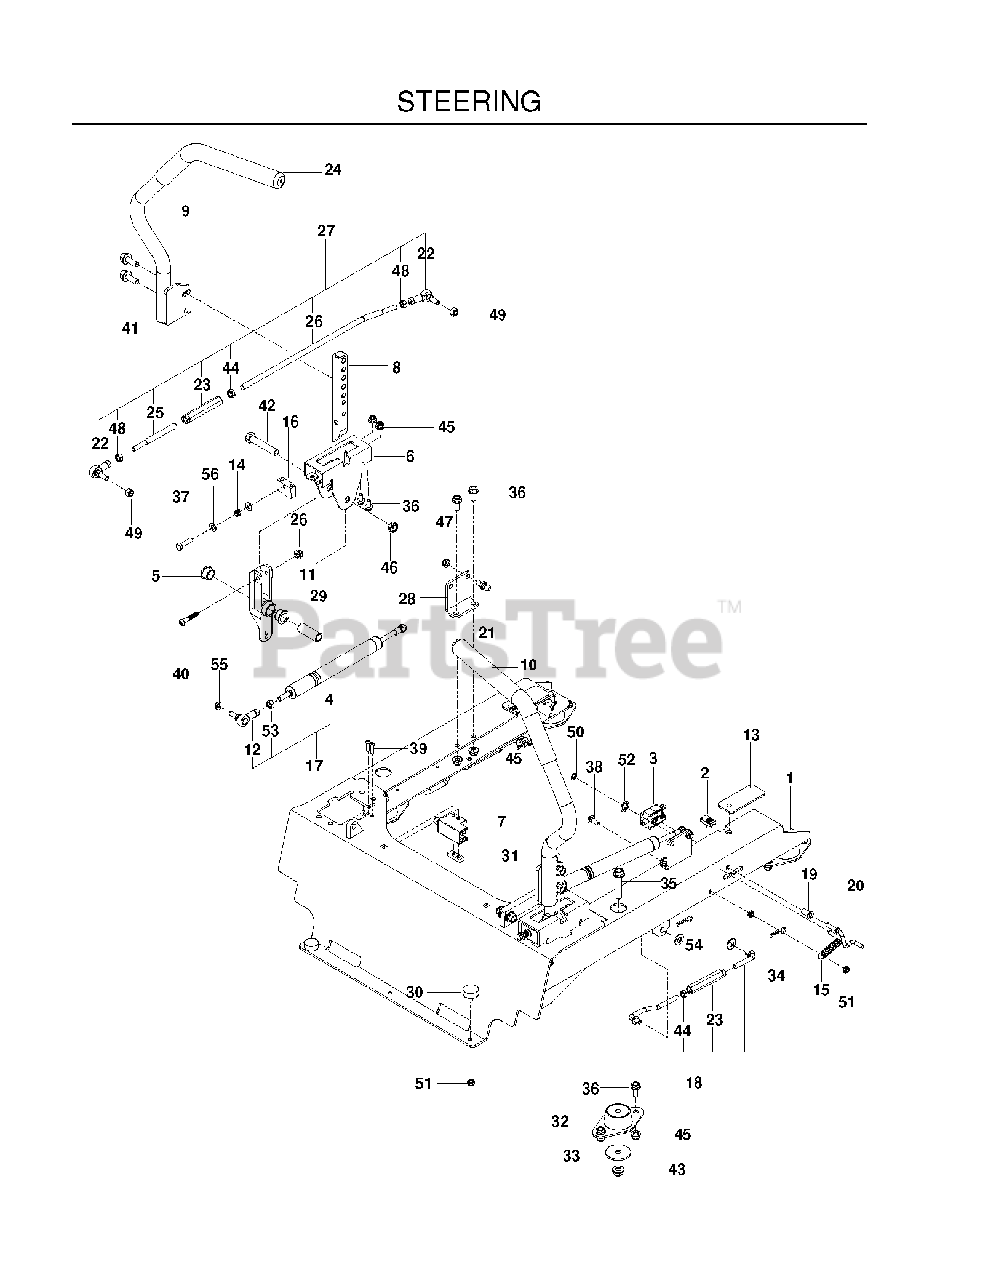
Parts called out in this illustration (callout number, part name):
2	U-CLIP 5/16-18 NUT RETAINER
3	SWITCH, BRAKE 3P
4	DAMPENER
5	BEARING, FLANGE
8	LEVER, MOTION
12	ROD END
15	SPRING, EXTENSION
17	ASSEMBLY, DAMPENER
18	ASSEMBLY, SEAT STRUT
19	BUSHING, 1/4 FLANGE
20	LINK, SWITCH
21	10MM BALL STUD
22	SPHERICAL ROD END, RH
23	TURNBUCKLE, 3/8
24	GRIP - DRIVE LEVER
25	LINKAGE, CONTROL, FT
31	TAPPED PLATE
33	WASHER, 3/8 SPEC
34	HAIRPIN #2
35	HHFS 3/8-16 X 2.0 GD 5
36	HHFS 5/16-18 X 3/4
37	HCS 5/16C X 1 1/4
38	RHSNB 1/4C X 3/4
39	SCR #10-24 X .75 SKT HD BLK
41	HHFS 3/8-16 X 1 GRD 5 ZD
42	HCS 5/16C X 2-3/4
43	NUT 3/8-16 HEX FLG NYLOC ZD
44	NUT 3/8-24 JAM
45	5/16-18 NYLOC FLANGE NUT
46	NUT 1/2-13 HEX JM NYL
47	NUT 5/16 NYLOC
48	NUT 5/16F
49	NUT 5/16F NYLOC
50	NUT PUSH
51	JAM NUT 1/4C
52	BOLT RETAINER 3/8
53	NUT M8 X 1.25 STD HEX
54	WASHER 3/8 SAE FLAT
55	WASHER 5/16 LOCK
56	FLAT WASHER 5/16 SAE
